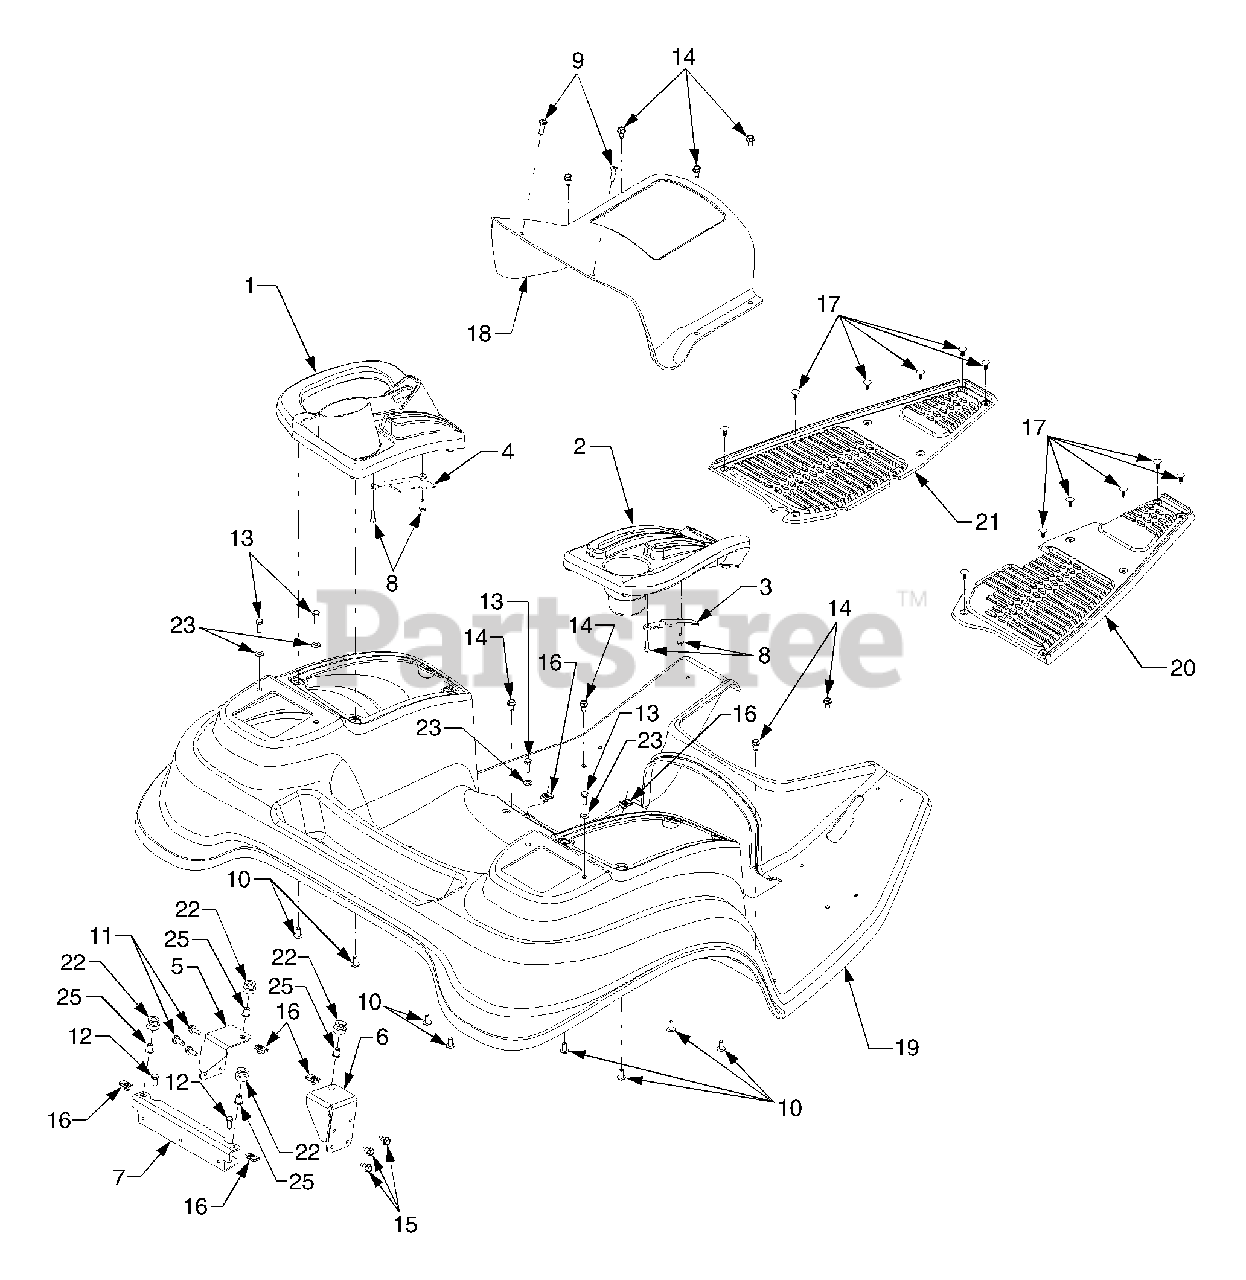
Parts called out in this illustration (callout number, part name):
1	Cover, Fender, LH
2	Cover, Fender, RH
6	Bracket, Seat Mtg. RH
7	Bracket, Rear Seat Support
8	Screw, Hex Wash Hd Tapp, 1/4-15 x .75
9	Screw, Pan Hd. 5/16-18 x 1.0
10	Screw, Truss Phillips Hd. 5/16-14 x .75
11	Screw, Hex Wash Hd. Tapp 5/16-18 x .75
12	Screw, Hex Cap 5/16-18 x .75 GR5
13	Screw, Hex Cap 5/16-18 x .875 GR5
14	Screw, Hex Wash Hd. Tapp 5/16-18 x .625
15	Screw, Hex Wash Hd. Tapp 5/16-18 x .625
16	Speed Nut, 'U' Type, 5/16-18
17	Clip, Ratchet Fastener
18	Cover, Fender
20	Pad, Floor, RH
21	Pad, Floor, LH
22	Grommet, .4375 ID x .75
23	Washer, Flat, .345 x 1.0 x .100
24	Spacer, Flange, .3125 x .4375 x .625
